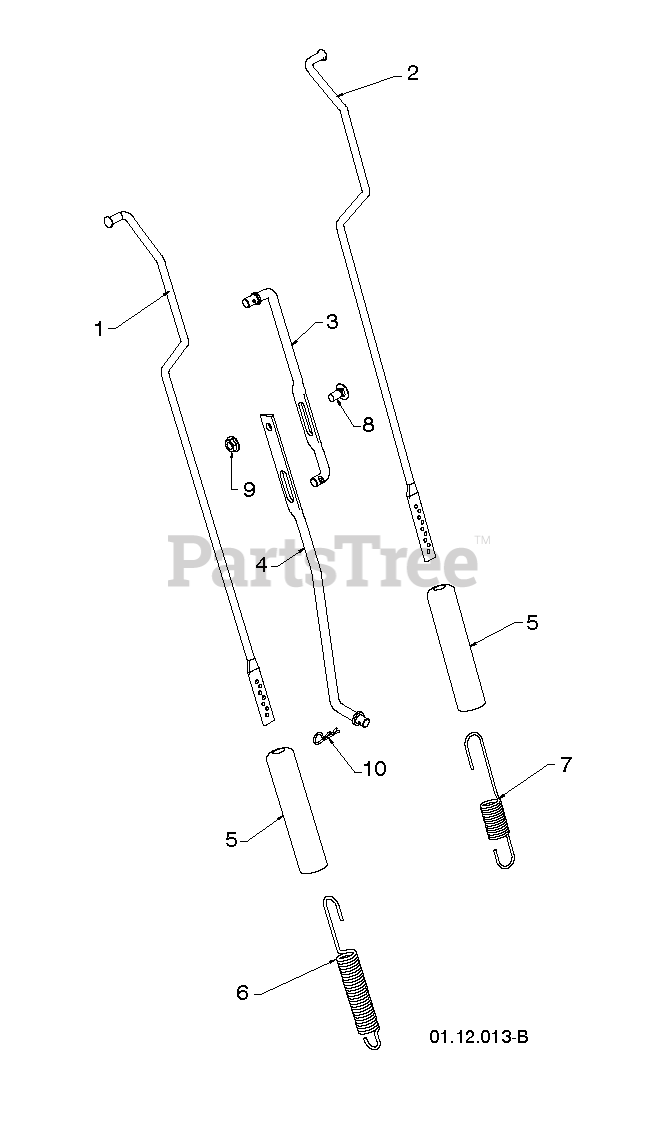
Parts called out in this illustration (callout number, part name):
1	ROD.IMPELLER
2	ROD.TRACTION
3	ROD, UPPER SPEED CONTROL
4	ROD, LOWER SPEED CONTROL
5	SLEEVE, SPRING
6	SPRING.CONTROL.ROD.SNOW
7	SPRING.TRACTION.ROD.SNOW
9	NUT.FLANGE.5/16
10	SPRING RETAINER
